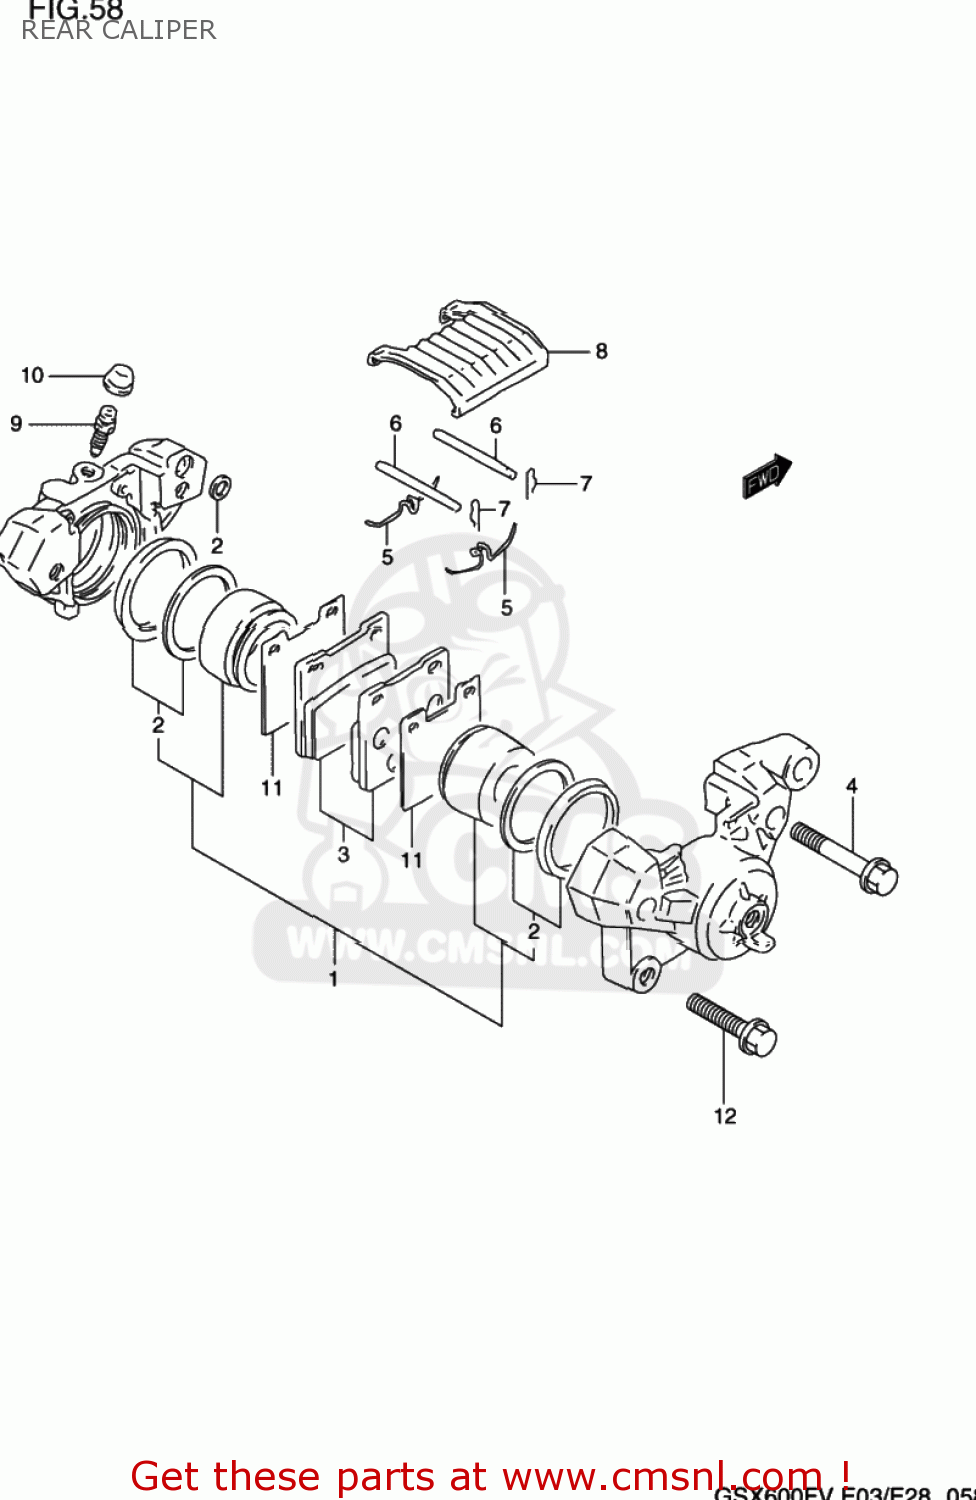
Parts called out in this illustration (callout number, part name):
1	PISTON SET
2	SEAL SET,PISTON
3	PAD SET (NAS)
4	BOLT,HOUSING
5	SPRING
6	PIN,PAD
7	CLIP,PAD PIN
8	COVER
9	BLEEDER
10	CAP,BLEEDER PLUG
11	SHIM,PAD
12	BOLT
